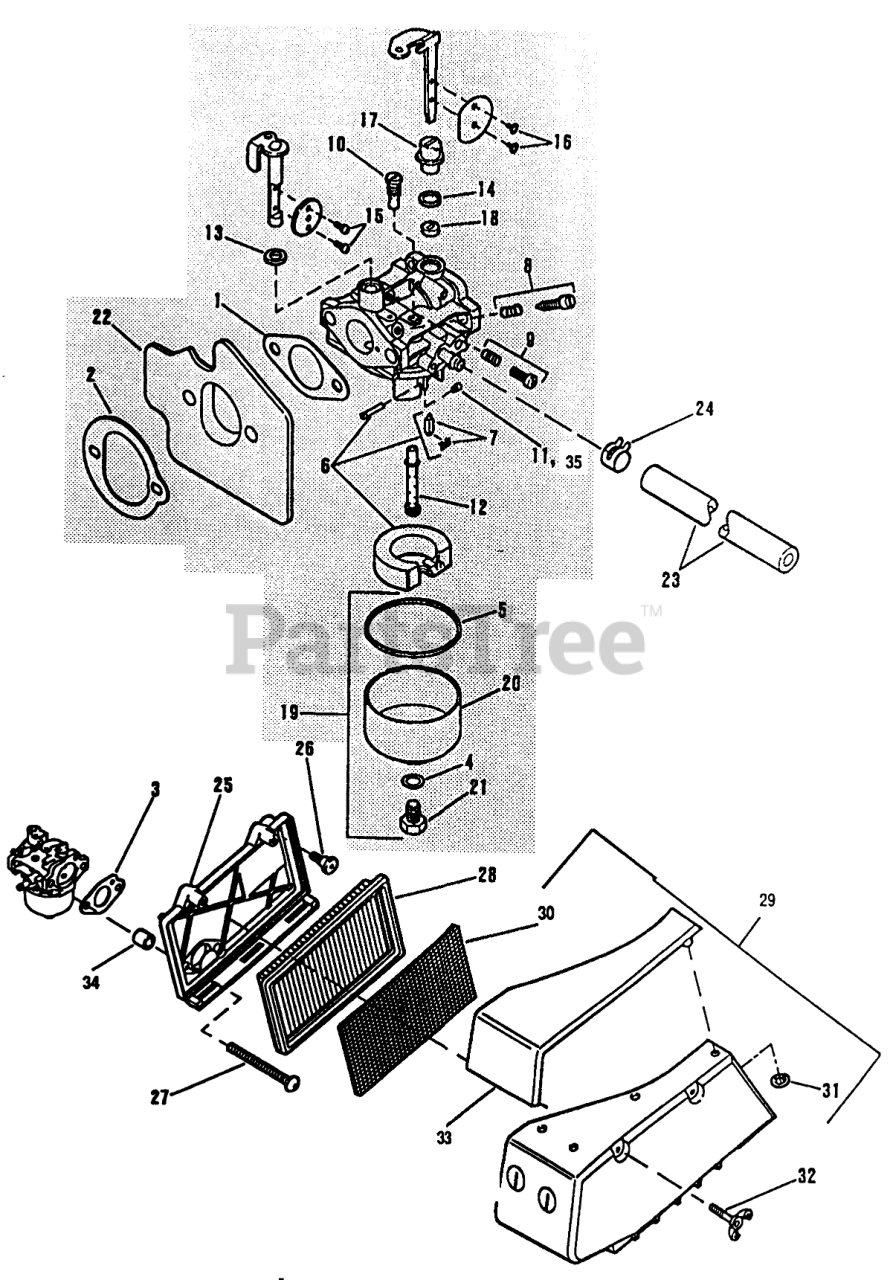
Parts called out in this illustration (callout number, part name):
1	GASKET SM
2	GASKET SM
3	GASKET-FIL SM
4	GASKET-BOWL RET S
5	GASKET-FUELBOWL S
6	FLOAT & NEEDLE S
7	NEEDLE & CLIP S
8	IDLE NEEDLE&SPRING
9	IDLE SPD.SCRW.KIT
10	PILOT JET
11	CARB JET
12	Nozzle
13	Thottle Shaft Seal
14	SEAL CHOKE SHAFT
15	SCREW THROT VALVE
16	SCREW CHOKE VALVE
17	PIVOT CHOKE SHFT
18	PIVOT CHOKE SHFT
19	BOWL KIT
20	Bowl-Fuel
21	SCREW,BOWL RET S
22	SPACER -CARB. SM
23	GAS LINE S
24	HOSE CLAMP SM
25	BASE-AIR FILT SM
26	BOLT SHOULDER SM
27	Screw
28	ELEMENT-AIR SM
29	AIR FILTER COVER
30	PREFILTER SM
31	NUT-PUSH
32	KNOB & SCREW
33	COVER-AIR BOX
34	SPACER SM
35	MAIN JET
